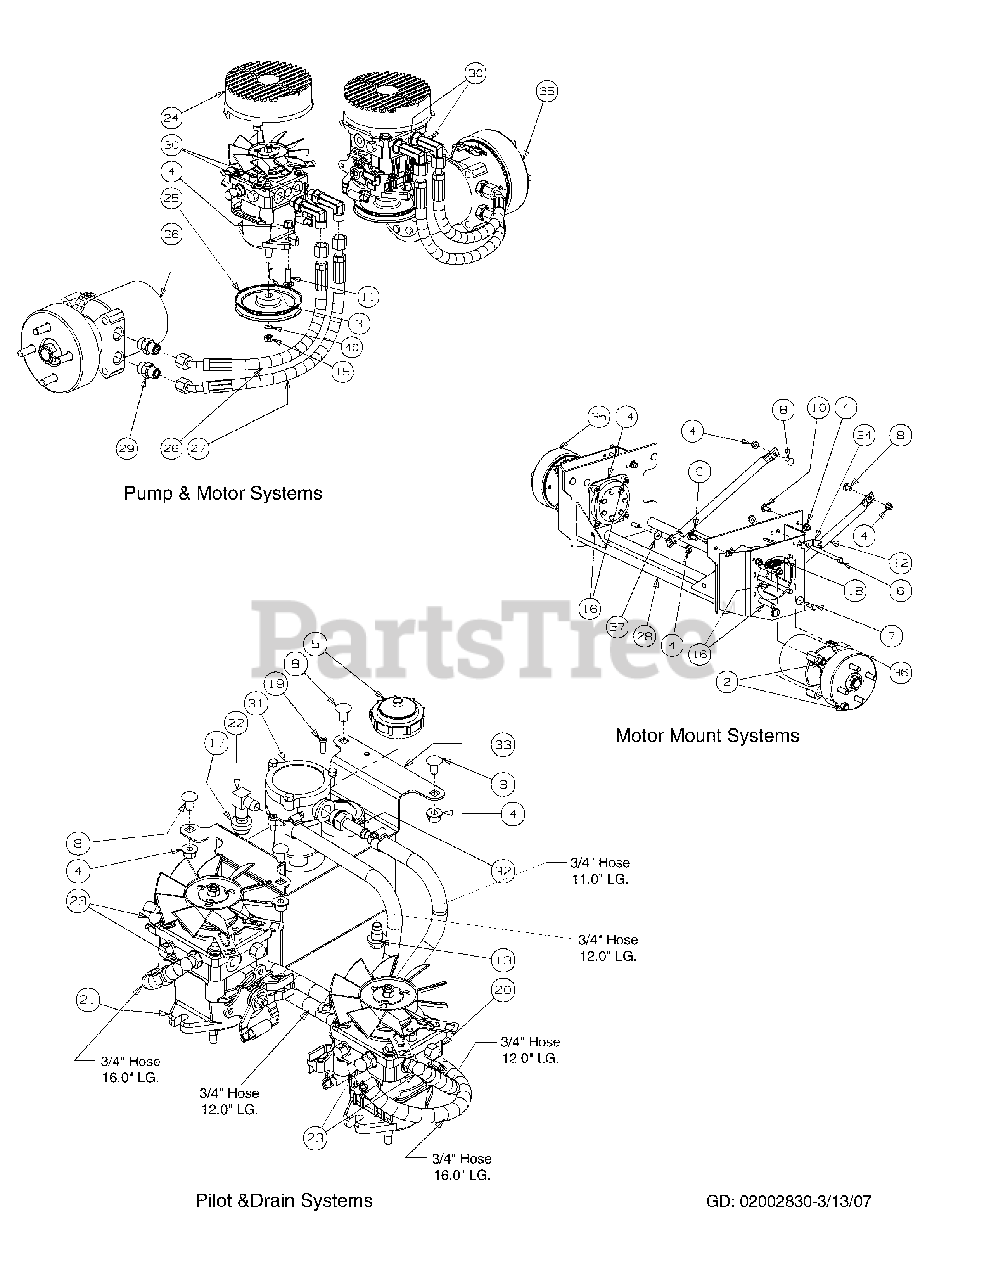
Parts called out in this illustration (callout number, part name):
1	Hose Clamp, 1/2
2	Washer lock 3/8 zinc
3	Key, 3/16" x 7/8"
4	Flange Lock Hex Nut, 3/8-16
5	Cap, Hydro Oil Tank
6	Hex Cap Screw 3/8-16 x 5.00
7	Hex Cap Screw, 3/8 -16 x 1.25
8	Carriage Bolt, 3/8-16 x .75 LG.
9	Carriage Bolt, 3/8-16 x 5.50
10	Carriage Bolt, 3/8-16 x 1
11	Carriage Screw, 3/8-16 x 1.25
12	Strut Frame
13	Oil Pan Drain Plug w/ Seal
14	Hydro Wheel Motor Backup Plate
15	Hex Nut, 3/8-24
16	Socket Head Capscrew, 1/2-13; 6-1/2
17	Grommet Fitting, .54 ID x .78 OD
18	Spring Extension, .740 OD x 2.656
19	Socket Low Head Cap Screw, 1/4-20 x 0.75
20	Hydro Pump, BDP-12, RH
21	Hydro Pump, BDP-12, LH
22	Fitting Elbow Spur, 5/8 x 1/2
23	Fitting Elbow, 9/16 x 1/2
24	Fan Pump Shroud
25	Hydro Pump Pulley
26	Short Pressure Hose Assembly
27	Long Pressure Hose Assembly
28	Hydro Motor Frame Assembly
29	Adaptor Fitting, 8 x 10
30	Adaptor, 8 x 8
31	Hydraulic In-Tank Filter includes:
32	Fitting, 3/4 ORB x 1/2 Tube
33	Hydraulic Tank Assembly
34	Rear Cable Mounting Bracket
35	Hydro Motor, Left Hand Assembly w/ Brake & Drum
36	Hydro Motor, Right Hand Assembly w/ Brake & Drum
37	Idler Washer
38	Fuel Hose, .50 ID x .75 OD (79 in inches)
39	Tee Fitting, 1/2
40	Flat Washer, 3/8
